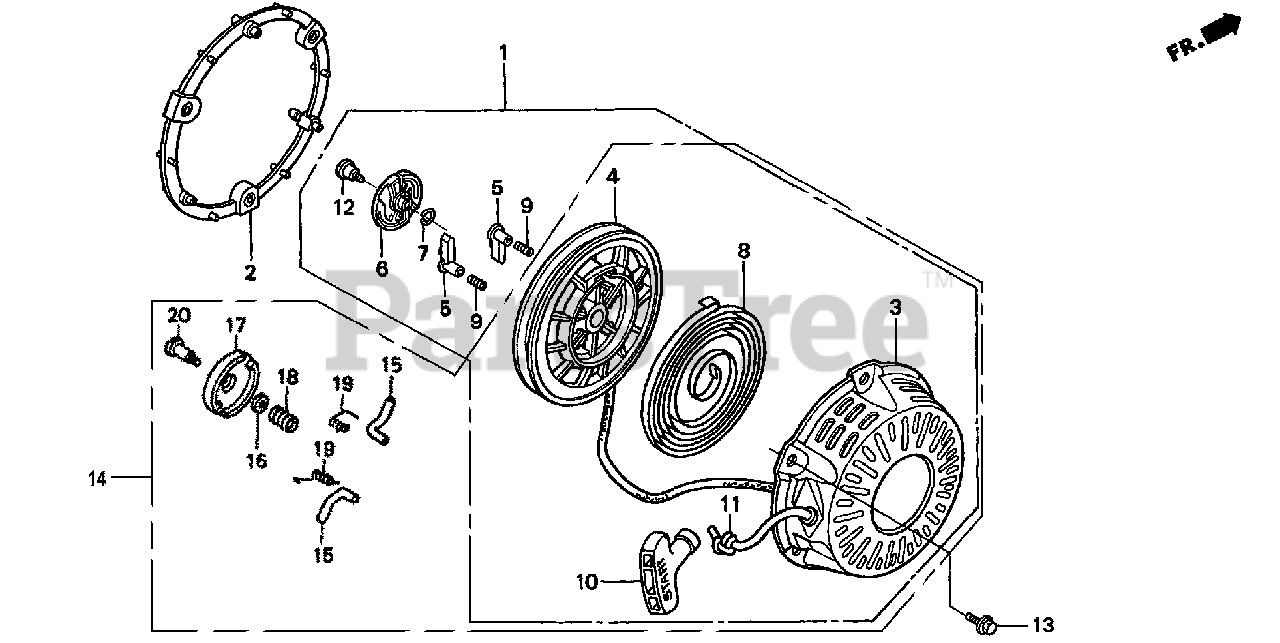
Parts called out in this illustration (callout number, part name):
1	STARTER ASSY., RECOIL *R280* (POWER RED)
1	STARTER ASSY., RECOIL *R8* (BRIGHT RED)
3	CASE, RECOIL STARTER *R280* (POWER RED)
3	CASE, RECOIL STARTER *R8* (BRIGHT RED)
4	REEL, RECOIL STARTER
5	RATCHET, STARTER
6	GUIDE, RATCHET
7	SPRING, FRICTION
8	SPRING, RECOIL STARTER
9	SPRING, RETURN
10	KNOB, RECOIL STARTER
11	ROPE, RECOIL STARTER (#5X55")
12	SCREW, SETTING
13	BOLT, FLANGE (6X10)
